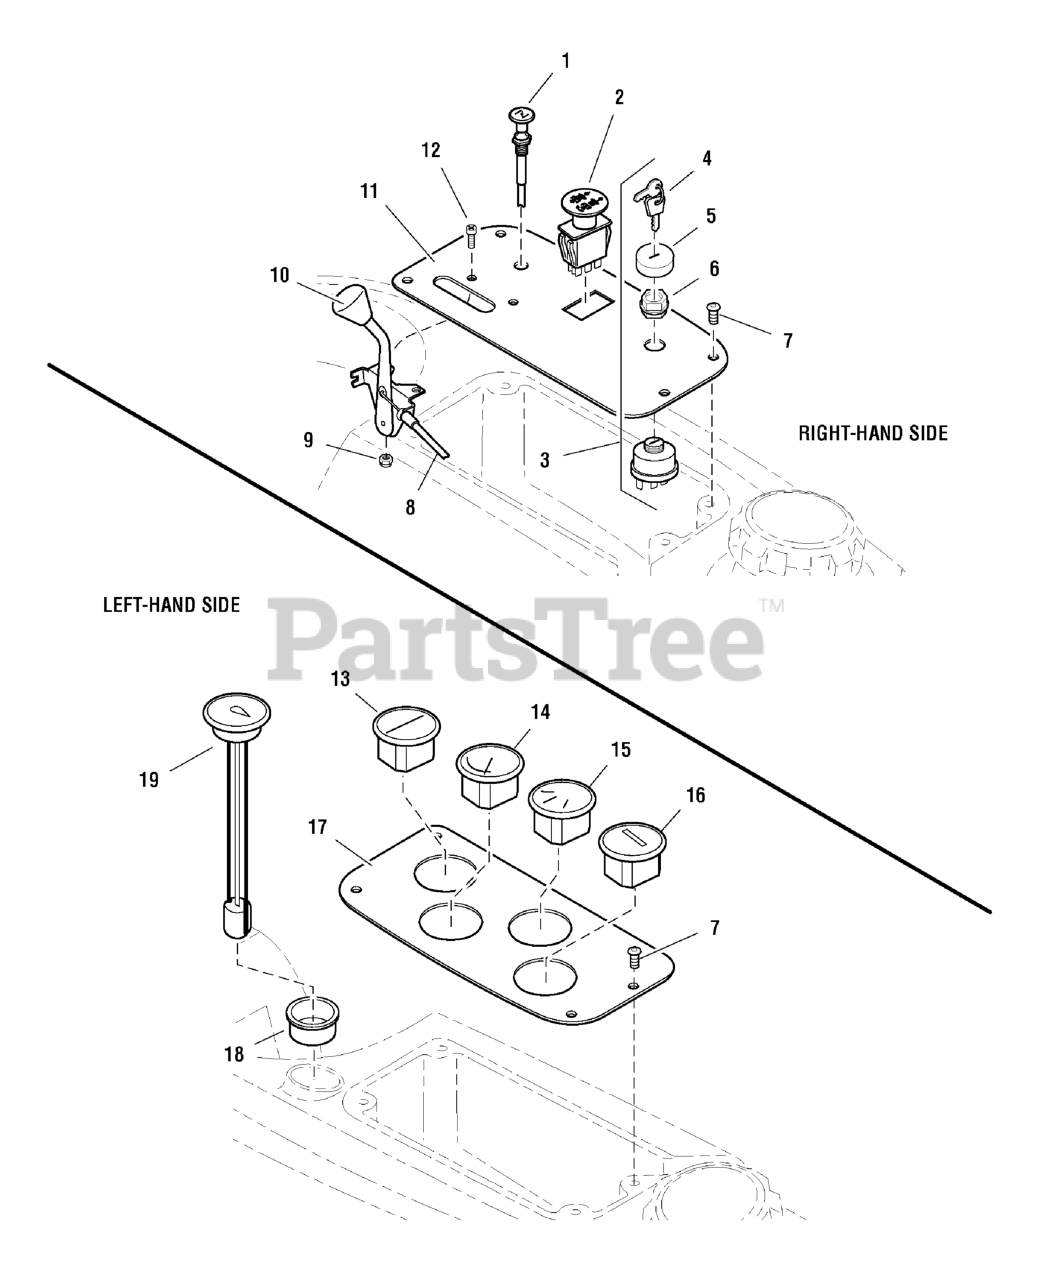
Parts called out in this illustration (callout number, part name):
1	CABLE, Choke Control
2	SWITCH, BLADE ENGAGEMENT
3	SWITCH, IGNITION, 6 POST
4	KEY, IGNITION MOLDED SET
5	COVER, PLASTIC, SNAP ON
6	PLASTIC NUT
7	SCREW, Allen Head, 1/4-20 x 1/2
8	CABLE, Throttle Control
9	NUT, #10-24 Hex Nylon Lock
10	HANDLE, THROTTLE CONTROL
10	THROTTLE CONTROL HANDLE/KNOB
11	CONTROL PANEL-RH
12	SCREW, #10-24 x 3/4
13	GAUGE, Warning, Oil/Temp
14	GAUGE, Water Temperature
15	GAUGE, Voltmeter
16	HOUR METER
17	PANEL, GAUGE CLUSTER (4)
18	GROMMET
19	GAUGE, FUEL, 12
